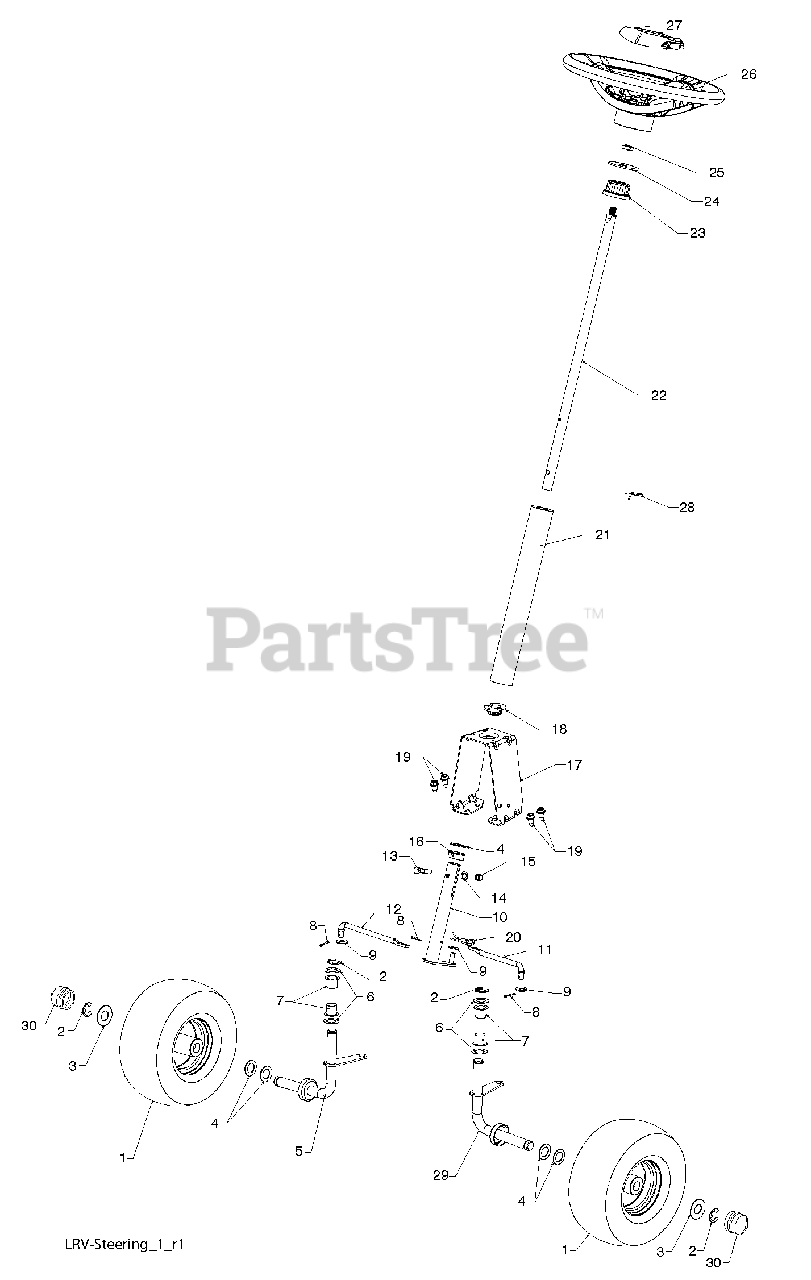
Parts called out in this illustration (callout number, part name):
1	WHEEL ASM (FRONT)
2	E-CLIP
3	WASHER, HARDENED
4	WASHER, 1/4 X 3/4
5	SPINDLE, RH
6	ASHER, HARDENED THRUST
7	USHING, STEERING COLUMN
8	PIN, 5/64 X 3/4 COTTER
9	WASHER
10	WELDMENT, LWR STRG SHAFT
11	LINK, STRNG LH
12	LINK, STRNG RH
13	BOLT, 5/16-18 X 1 1/2
14	WASHER
15	NUT, 5/16-18
16	BUSHING, STEERING SNAP
17	SUPPORT, UPPER STEERING
18	BUSHING, UPPER STEERING
19	BOLT, 5/16-18 X 3/4
20	CLIP, RETAINER SPRING
21	COVER, STEERING COLUMN
22	SHAFT, STEERING
23	ADAPTER, STEERING WHEEL
24	WASHER, 9/16 X 2 3/8 12 GA.
25	NUT, JAM LOCK 1/2-20
26	WHEEL, STEERING
27	CAP, STEERING WHEEL
28	CLIP, RETAINER SPRING
29	SPINDLE, LH
30	CAP, HUB, AXLE
